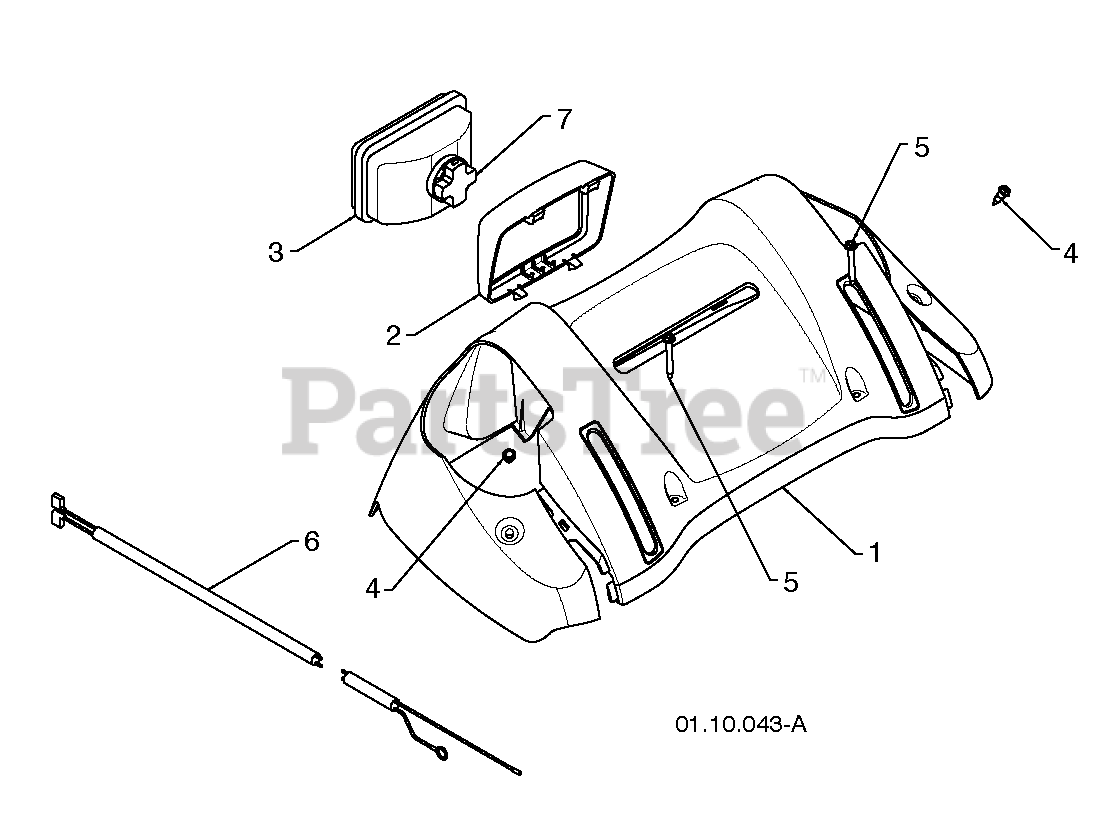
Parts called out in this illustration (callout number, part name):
1	Console Panel Gray
2	Headlight Bezel Gray
3	Flood Headlight
4	Shoulder Screw 10-24 X .625
5	Screw 10-24 X 1.25
6	Wire Harness
